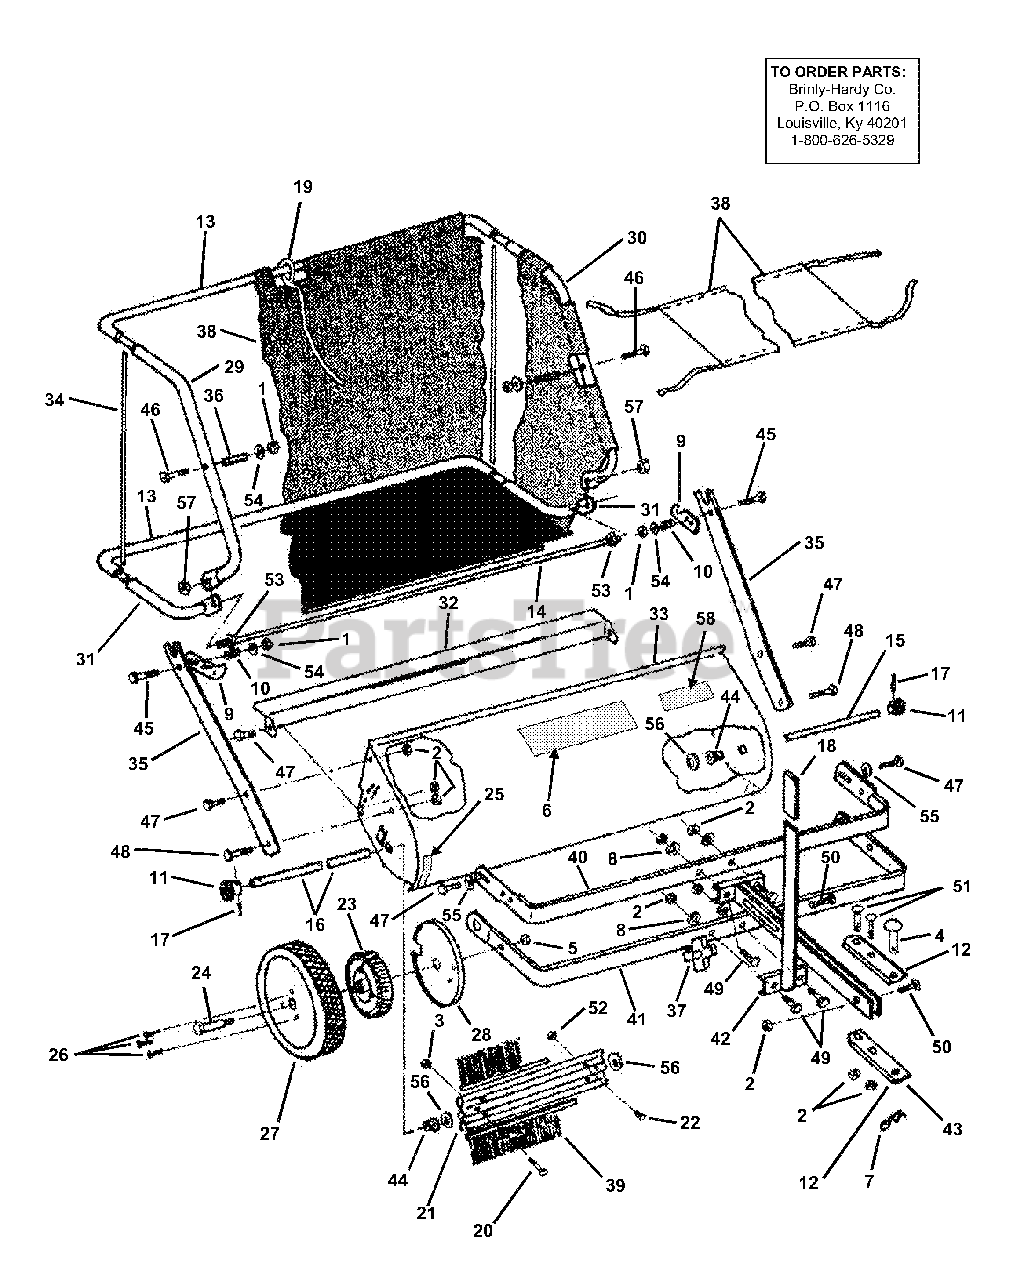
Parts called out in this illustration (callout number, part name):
1	NUT, 1/4" Hex Lock
2	NUT, 5/16" Hex Lock
3	NUT, #10 Hex Lock
4	HITCH PIN, 1/2 x 2-1/4"
5	NUT, 3/8' Hex Lock
6	DECAL, Logo
7	HAIR PIN COTTER
8	WASHER, 5/16" Special
9	LATCH, Frame
10	SPRING, Latch
11	DRIVE PINION
12	CLEVIS, Drawbar
13	REAR TUBE Top & Bottom
14	STOP ROD
15	AXLE, Long
16	AXLE, Short
17	DRIVE PIN
18	GRIP, Handle
19	PULL ROPE
20	SCREW, #10 x 7/8" Machine
21	BRUSH HOLDER HALF
22	SCREW, #10 x 1/2"
23	GEAR, Drive
24	BOLT, 1/2" Shoulder
25	DECAL, Height Adjust
26	SCREW, 1/4 x 3/4" Pan Head
27	ASS'Y, Wheel & Tire
28	SHIELD, Dust
29	UPPER TUBE (R. H.)
30	UPPER TUBE (L. H.)
31	LOWER TUBE
33	ASSEMBLY, Housing
34	ROD, Hamper
35	BAR, hamper Support
36	SPACER, Hamper
37	KNOB, Adjusting
38	SCREEN, Hamper & Wind
39	SECTION, Brush
40	TUBE, Tow Bar Support
41	TUBE, Wheel Support
42	ASSEMBLY, Handle
43	ASSEMBLY, Tow Bar
44	BEARING, Bronze
45	BOLT, 1/4 x 1-1/2" Hex
46	BOLT, 1/4 x 2" Hex
47	BOLT, 5/16 X 3/4" Hex
48	BOLT, 5/16 x 1" Hex
49	BOLT, 5/16 x 1-1/4" Hex
50	BOLT, 5/16 x 1-1/4" Carr.
51	BOLT, 5/16 x 2" Carr.
52	NUT, #10 Hex
53	NUT, 3/8" Hex
54	WASHER, 1/4' Flat
55	WASHER, 5/16" Flat
56	WASHER, 1/2" Flat
57	NUT, 3/8" Hex Lock
58	DECAL, Instructions
